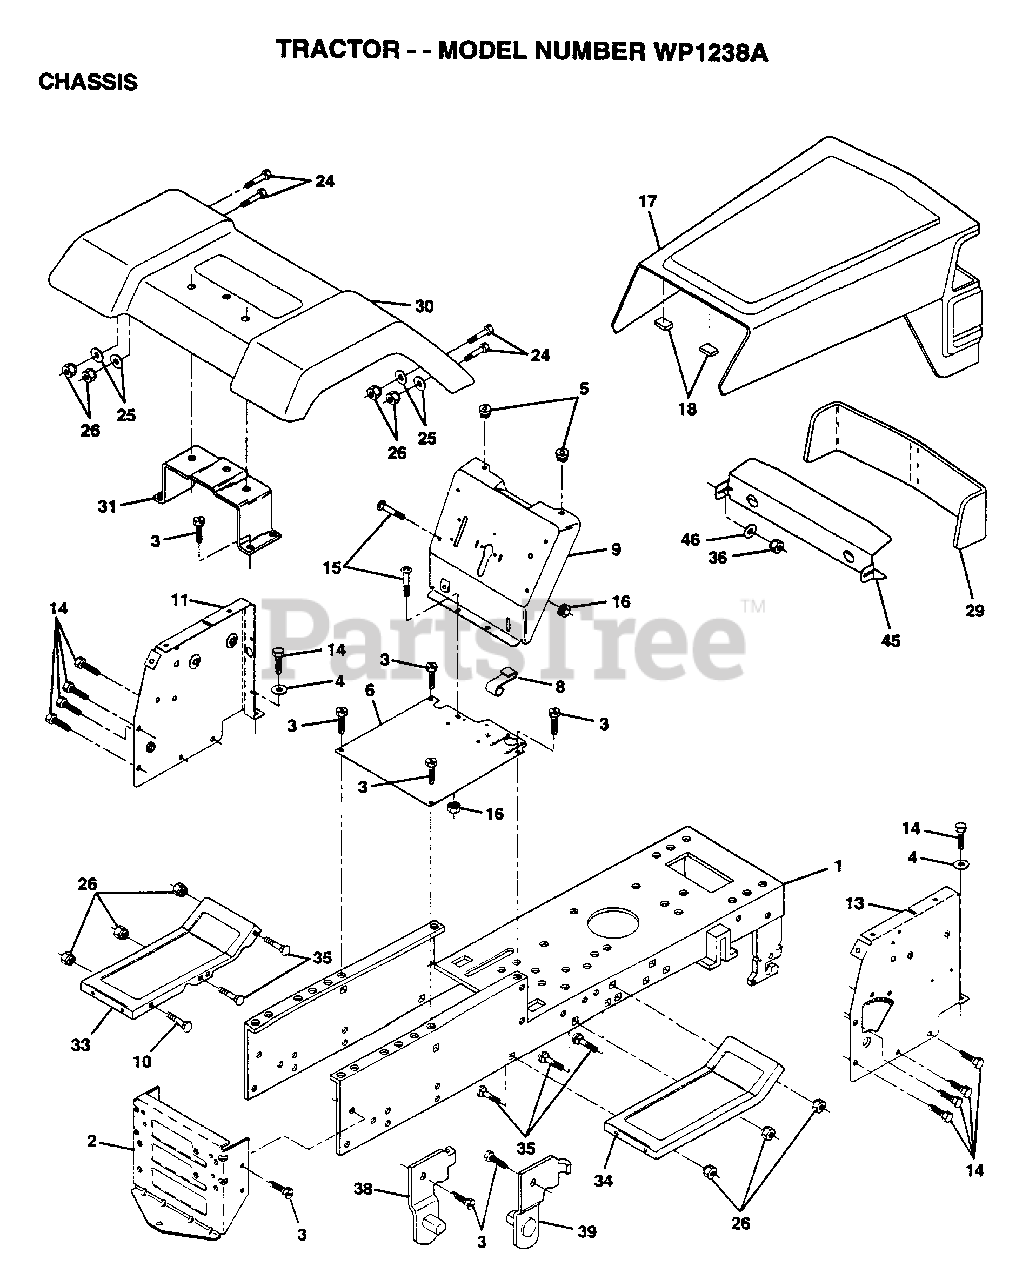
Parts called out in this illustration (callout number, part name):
1	CHASSIS.WLD.11GA
3	SCREW
4	WASHER
8	"CLIP,INSULATOR"
9	DASH.SLKSCRN.1PC.
11	PANEL.DASH.LH.
14	SCREW LT
15	SCREW
17	HOOD/GRILLE.ASM.
24	BOLT
25	WASHER
26	NUT
31	BRACKET SUPT FEND
33	FOOTREST.LH.LT/GT
34	FOOTREST.RH.LT/GT
35	BOLT
36	PAL NUT LT
38	BRACKET ASM LH
39	BRACKET ASM RH
46	RETAINER
